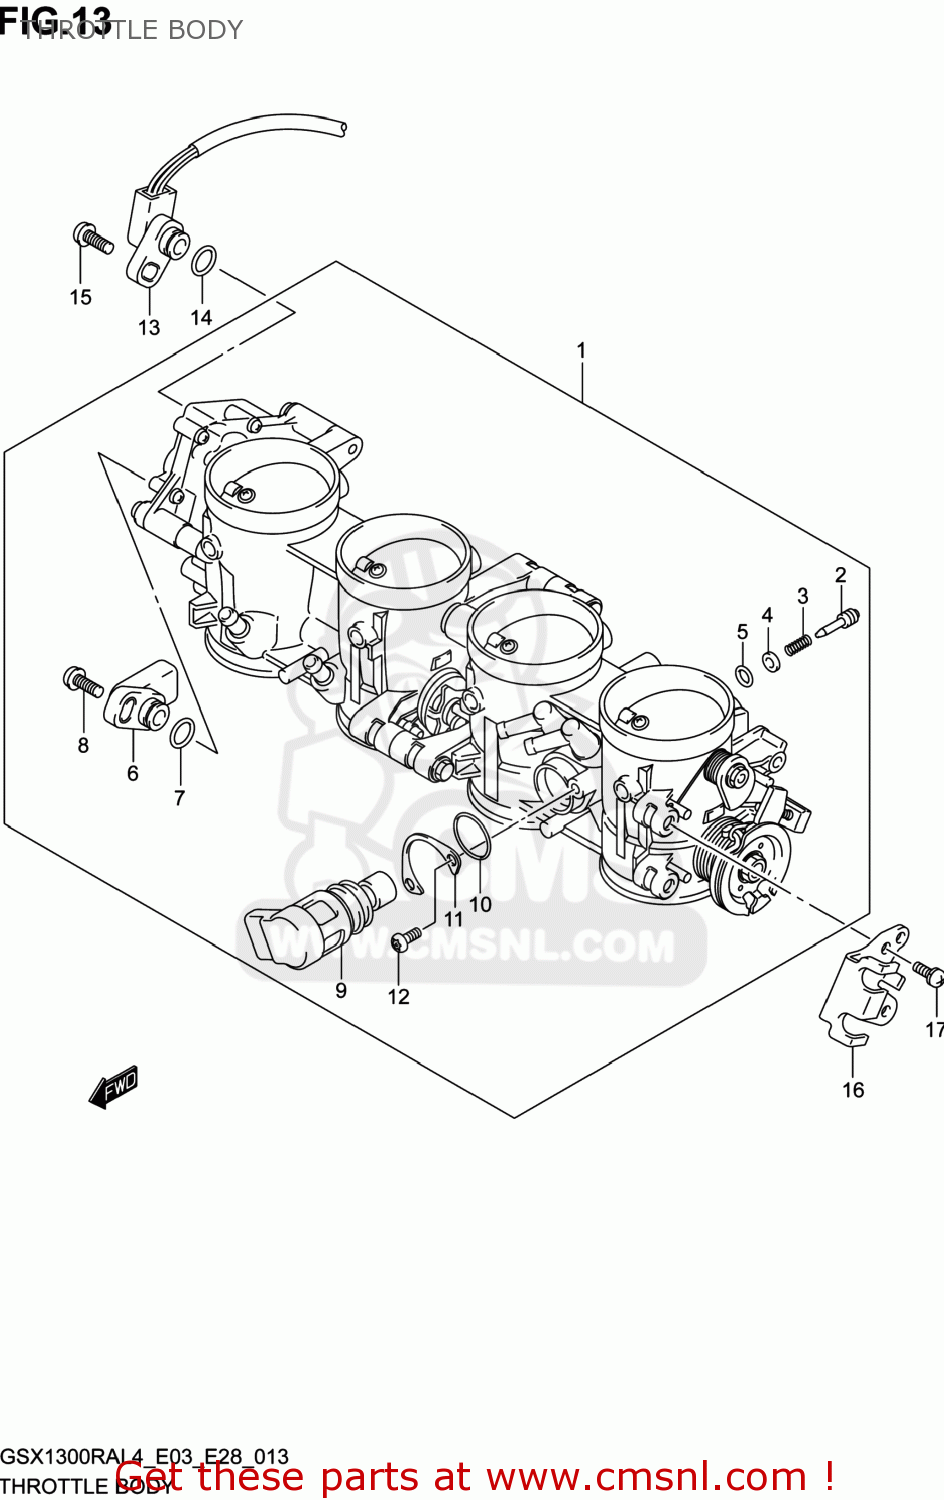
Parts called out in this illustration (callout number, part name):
1	BODY ASSY,THROTTLE
2	SCREW,AIR ADJUST
3	SPRING
4	WASHER
5	O RING
6	SENSOR ASSY,THROTTLE MAIN
7	O RING
8	SCREW
9	VALVE ASSY,ISC
10	O RING
11	PLATE,ISC VALVE
12	SCREW
13	SENSOR ASSY,THROTTLE NO.1
14	O RING
15	SCREW
16	PLATE,STAY
17	SCREW
